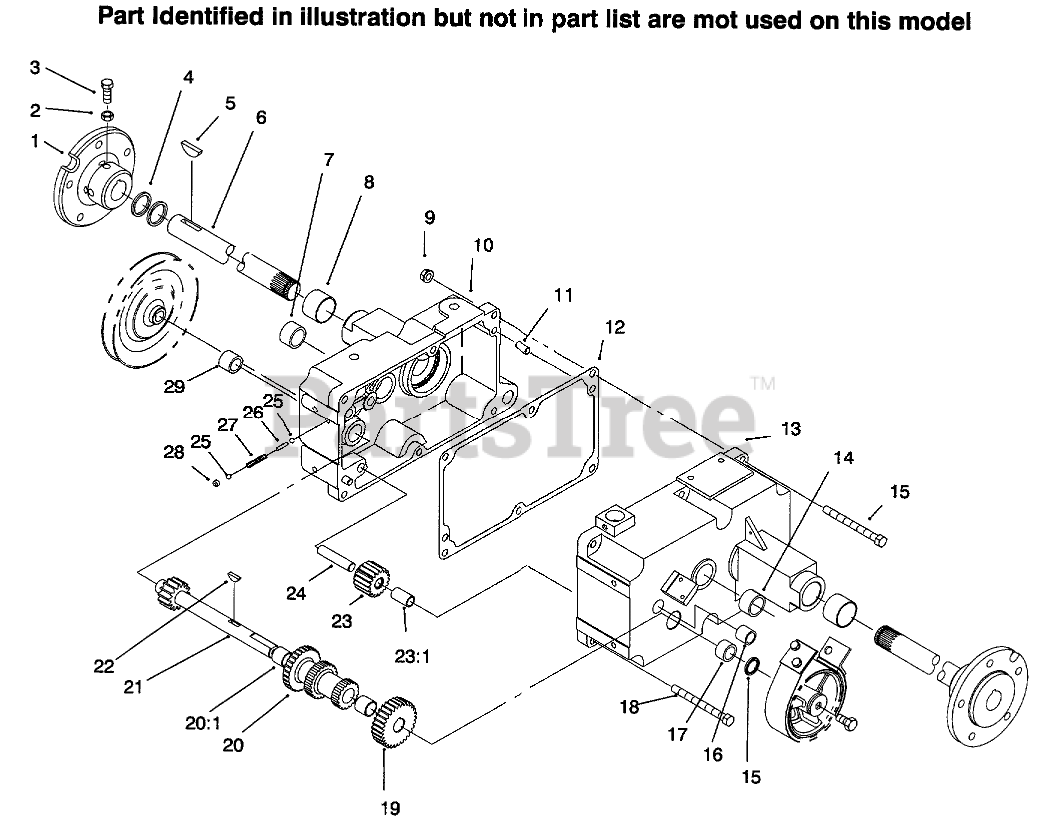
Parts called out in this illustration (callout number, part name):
1	Hub Rear
2	NUT-JAM
3	SCREW-SET, SQH
4	SEAL-OIL
5	KEY-WOODRUFF
6	AXLE-REAR
7	BEARING-NEEDLE
8	BEARING
9	NUT-LOCK, NI
9:9	PINION SHAFT
10	Case Trans RH
11	PIN-DOWEL
12	GASKET-TRANSMISSION
13	Case Trans LH
14	SCREW-HH
15	SEAL-OIL
16	SCREW-HH
16	BEARING-NEEDLE
17	BEARING-NEEDLE
19	SHIFT FORK ASM
19	GEAR-CLUSTER SHAFT
19	Shift Fork
20	GEAR-CLUSTER
20:1	BUSHING-BRONZE
21	SHAFT-CLUSTER
23	GEAR/BUSHING ASM-REVERSE IDLER
23	Gear-Spur
23:1	BUSHING
24	PIN-DIFFERENTIAL
24:1	Shift Lever
24:2	Shaft-Lever
26	PIN-SHIFT
27	SPRING-SHIFT STOP
28	CUP-PLUG
29	BEARING-NEEDLE
56	GEAR-SLIDING
